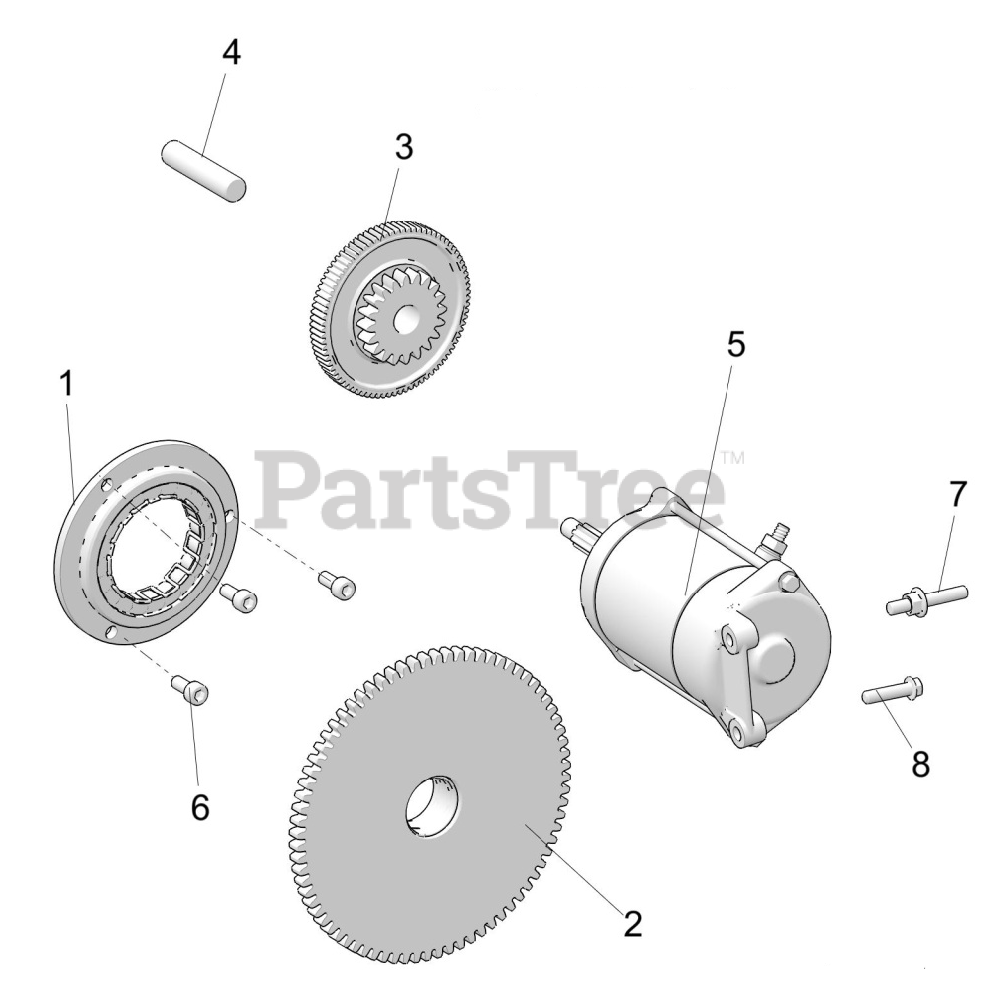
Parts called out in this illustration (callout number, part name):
1	ASM-SPRAG CLUTCH-HUB-STARTER
2	ASM-GEAR-STARTER-CRANK
2	ASM., GEAR, STARTER , CRANK
3	ASM., TLG
4	PIN-TQ- LIMIT- GEAR
5	STARTER-9T- CW
7	STUD-DOUBLE-END-M6X1.0X25/10
8	SCR-HXFLG-M6X1.0X25-10.9
